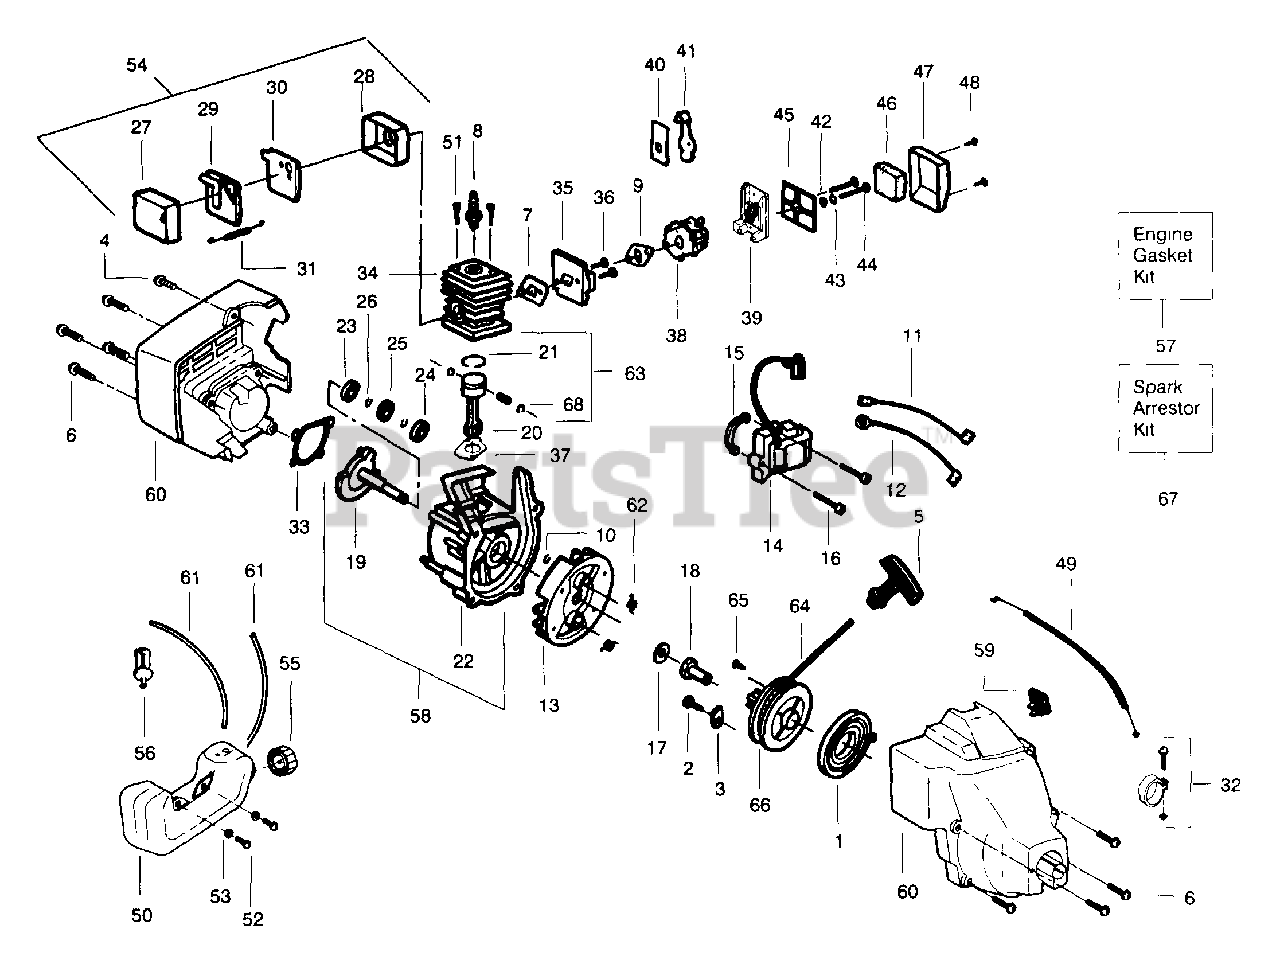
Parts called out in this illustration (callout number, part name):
1	Starter Spring
2	Screw - Pulley
3	Retainer - Pulley
4	Screw - Shrd/Fan Hsg
5	Starter Handle
6	Screw
7	Gasket - Cylind./Carb
8	Spark Plug (RCJ-BY)
9	Gasket - Carb.
10	Retainer Ring - C'case
11	Lead Wire Ass'y
12	Ground Wire Ass'y
13	Flywheel Ass'y
14	Ignition Module
15	Spacer - Ignit. Module
16	Screw - Ignit. Module
17	Washer - Flat
18	Drive Coupling
19	Crankshaft Ass'y
20	Connecting Rod Ass'y
21	Piston Ring
22	Crankcase Ass'y
23	Inner Bearing
24	Outer Bearing
25	C'case Seal
26	Retain Ring - C'shaft
27	Muffler Body
28	Muffler Cover
29	Muffler Baffle - Exit
30	Muffler Baffle - First
31	Muffler Spring
32	Nose Cone Clamp Assy
33	Gasket - C'case
34	Cylinder Kit
35	Carb Adaptor
36	Screw - Carb Adaptor
37	Gasket - Cylinder
38	Carburetor Ass'y Kit
40	Choke Plate
41	Choke Shutter
43	Choke Spacer
45	Filter Plate
46	Air Filter Foam
47	Air Filter Cover
48	Screw - Air Box
49	Throttle Cable Ass'y
50	Fuel Tank Ass'y
51	Screw - Cylinder
52	Screw - Fuel Tank
53	Washer - Fuel Tank
54	Muffler Kit
55	Fuel Cap Ass'y
56	Fuel Pickup Ass'y
57	Engine Gasket Kit
58	C'case & C'shaft Assy
59	On/Off Switch
60	Fan Housing/Shroud Ass'y
61	Fuel Line Kit
62	Starter Dog Spring
63	Piston Kit
64	Rope Kit
66	Starter Pulley Kit
67	Spark Arrestor Kit
68	Piston Pin Retainer
